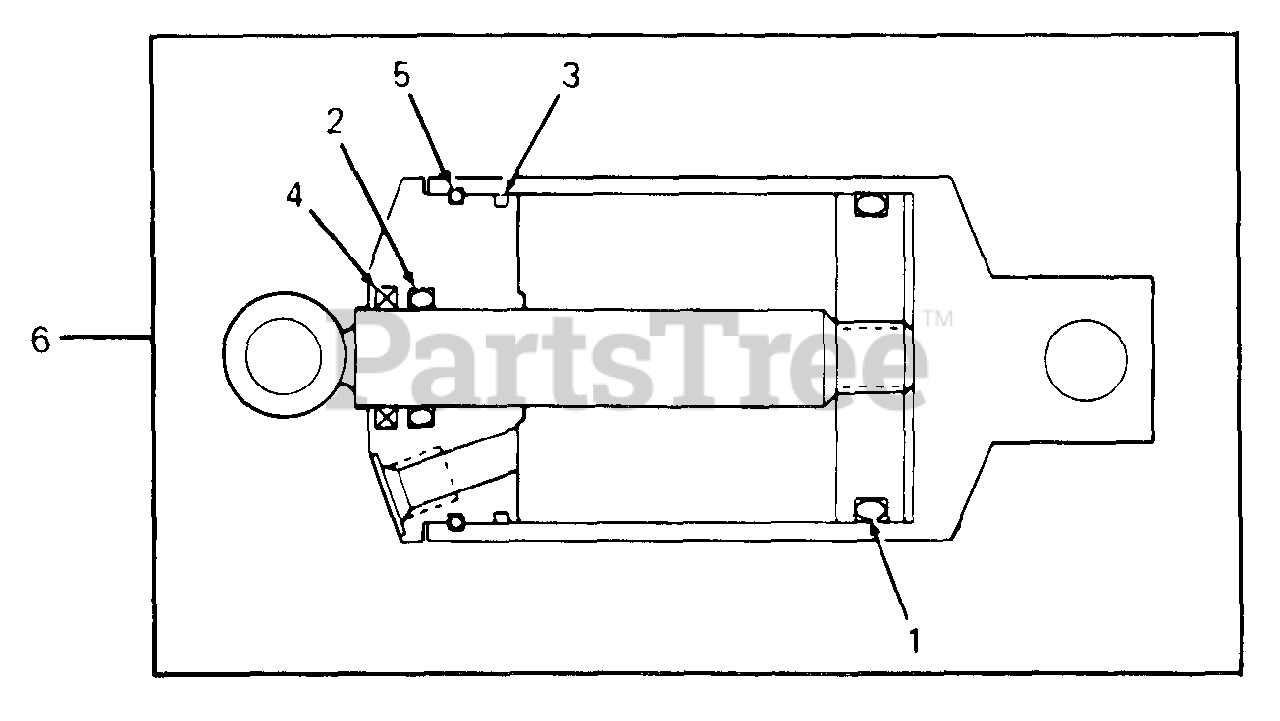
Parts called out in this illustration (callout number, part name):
4	Seal, Hydraulic Cylinder Piston Rod Wiper
5	Retainer, Hydraulic Cylinder Front Head
6	Cylinder, Hydraulic
